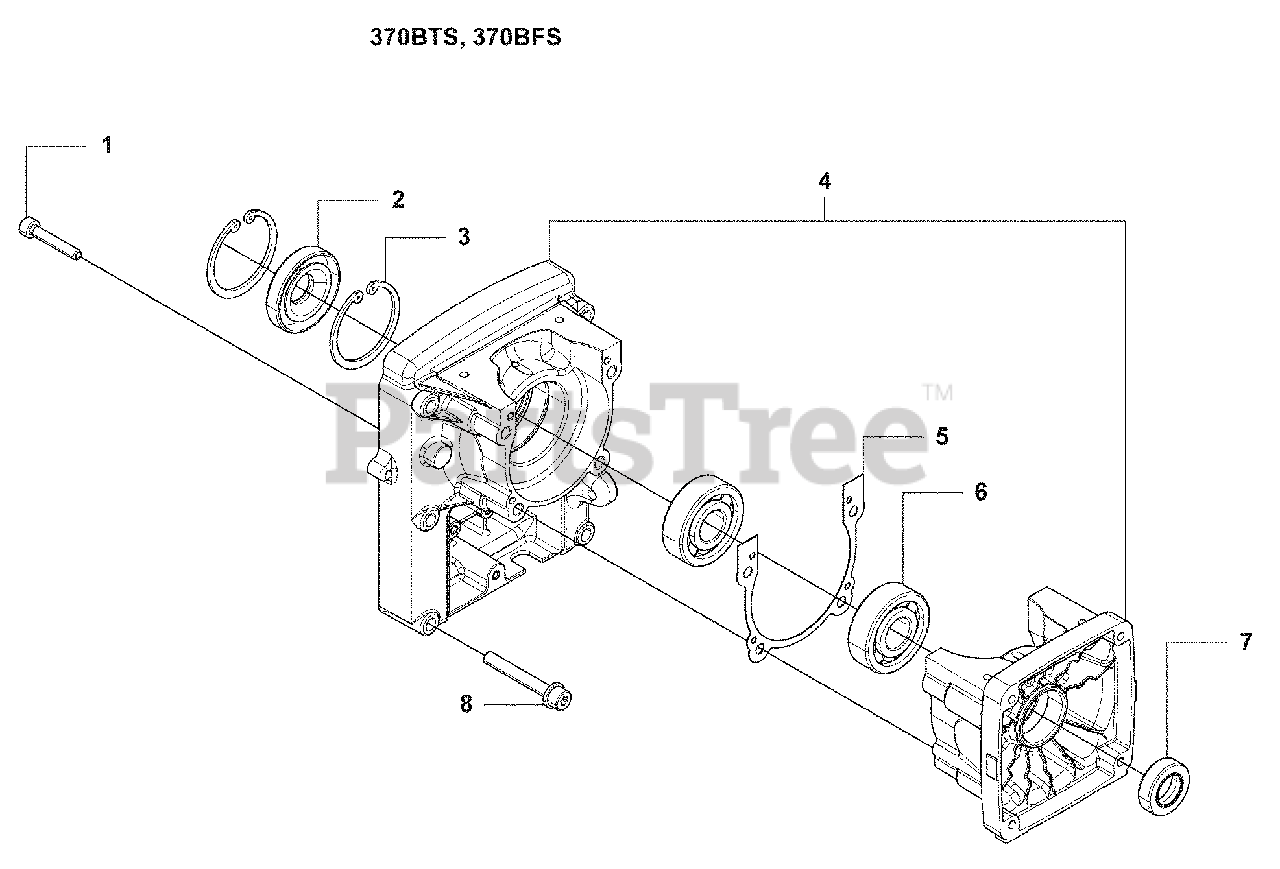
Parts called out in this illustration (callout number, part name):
1	Bolt
2	Seal
3	Snap Ring
4	CRANKCASE-C
5	Gasket
6	Ball Bearing
7	Seal
8	Bolt
